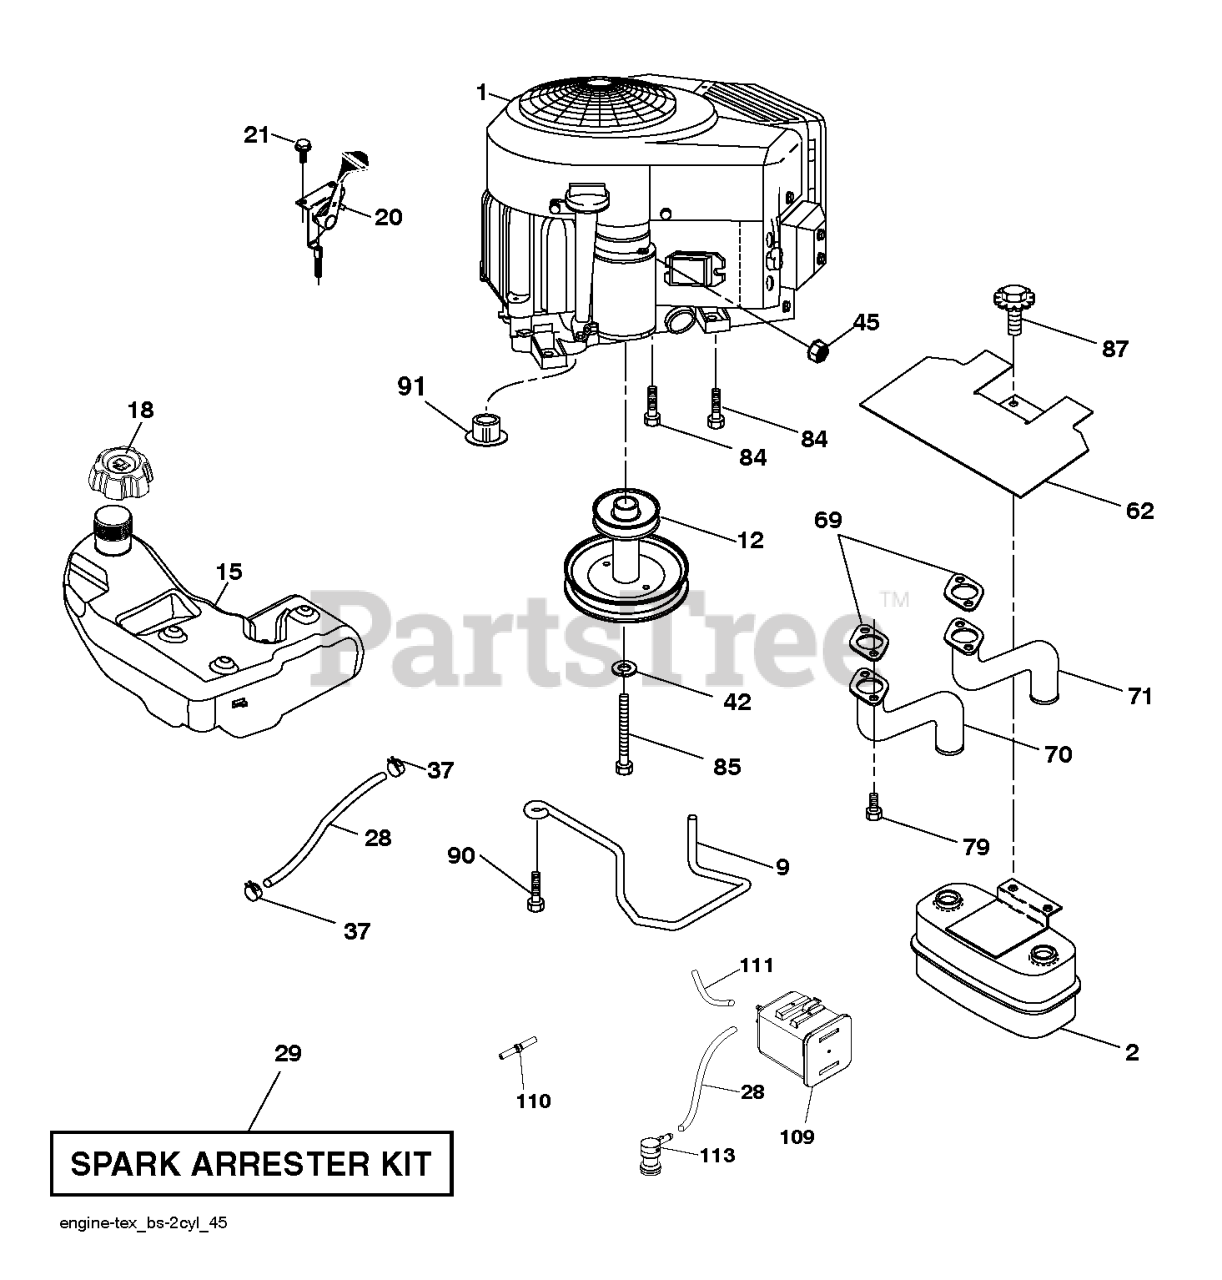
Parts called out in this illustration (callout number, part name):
2	MUFFLER.TWIN.CYL.LOW.TONE
9	KEEPER.BELT.ENGINE.4.2
12	PULLY ENGINE
15	TANK ASM.FUEL.3
18	CAP.ASM.FL.RITCH.3"E10.SYM.498
20	CONTROL.TH/CK.COBRA.B&S.TWN.BK
21	SCREW.#10 X 0.750.BOS
28	LINE.FUEL.64"REAR.EMIS
29	KIT.SPARK ARRESTOR 794945 B&S
37	HOSE CLAMP
42	LOCKWASHER
45	NUT
62	SHIELD.HEAT.MUFFLER
69	GASKET.MUFFLER
70	EXHAUST.TUBE.LH.BS/TWIN
71	EXHAUST.TUBE.RH.B&S.TWIN.INTEK
79	SCREW.SOCKET.HEAD.5/16-18
84	SCREW.3/8-16
85	BOLT HEX 7/16-20X4-1/4"
87	BOLT.5/16-18UNCX3/4 W/SEMS.BLK
90	SCREW 3/8-16X1
91	BUSHING.1.375OD
109	CANNISTER, CARBON
110	VALVE.ASM.ANTI-SLOSH
111	RP PURGE LINE
113	VALVE.SLANT.CARTRDG.90 DEG.TEX
